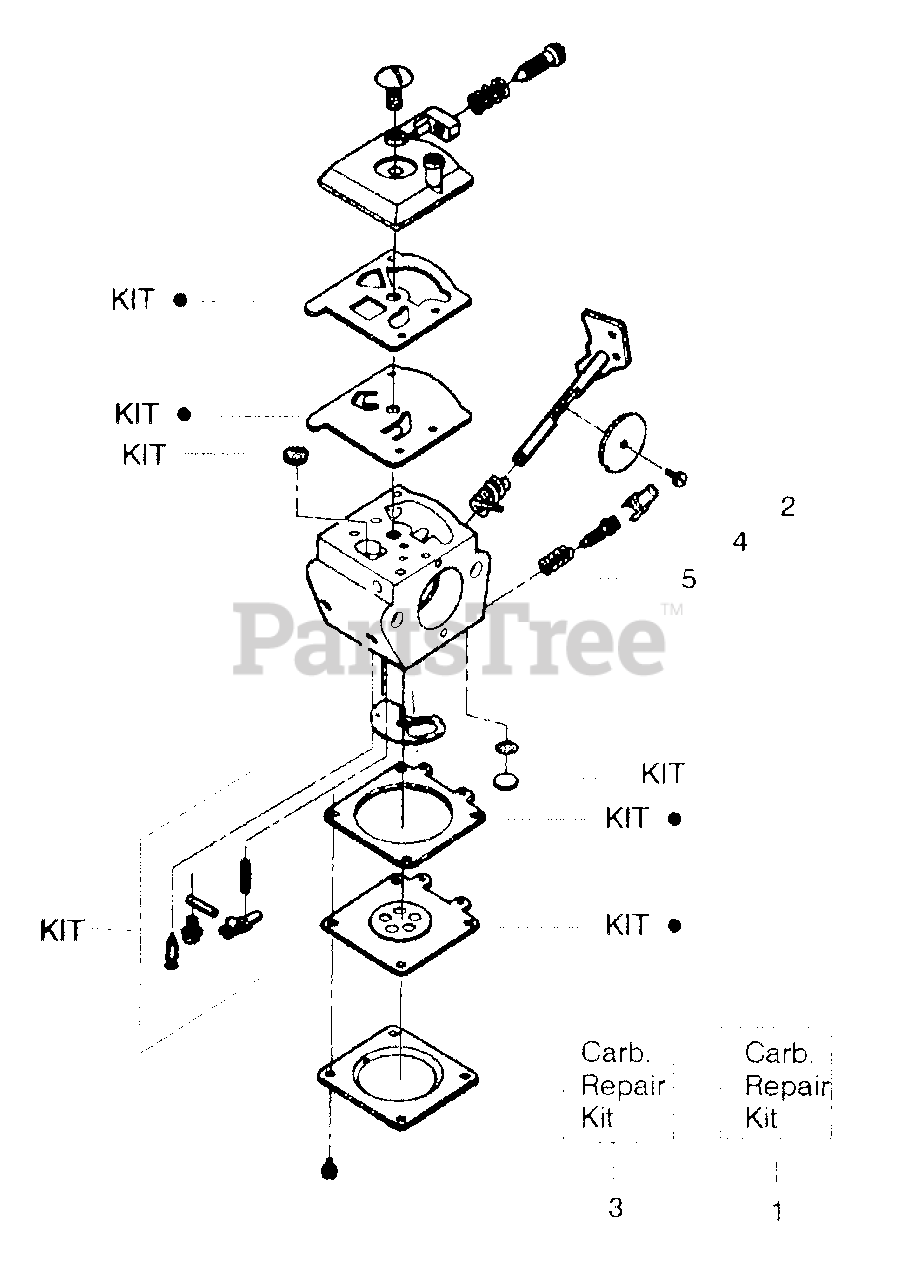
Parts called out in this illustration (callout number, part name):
1	Carburetor Repair Kit
2	Limiter Cap
3	Gasket/Diaphragm Kit
4	Needle-Fuel Mixture
5	Spring-Fuel Mixture
